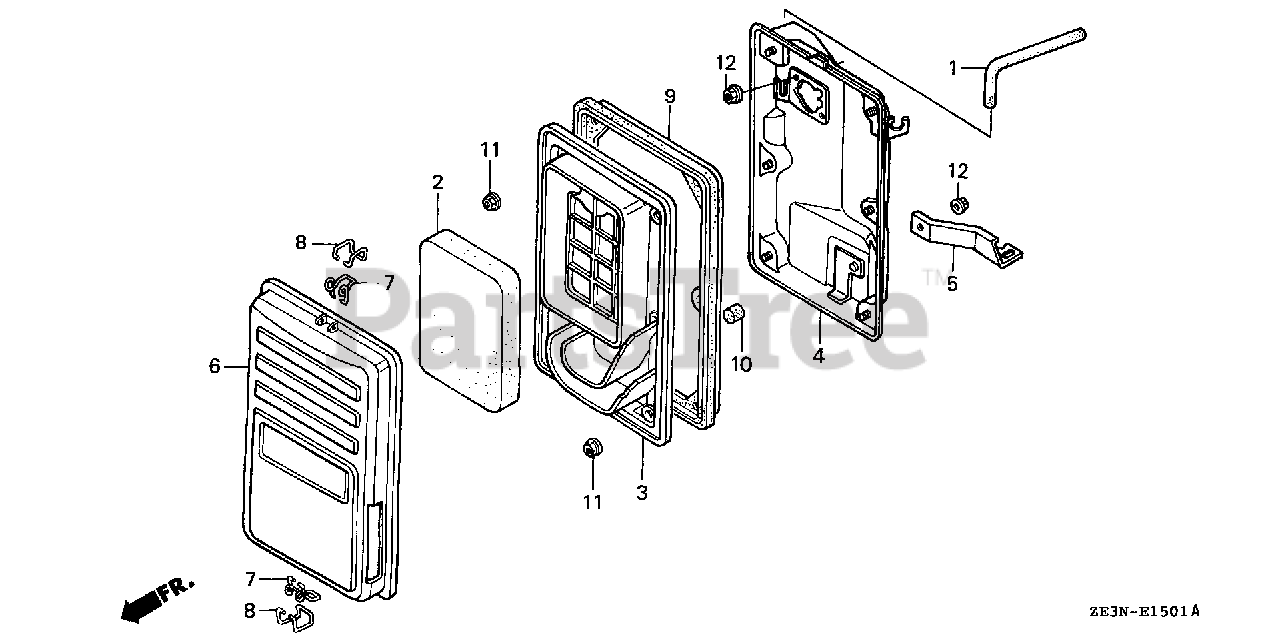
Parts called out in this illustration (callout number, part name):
1	TUBE, BREATHER
2	ELEMENT, AIR CLEANER
3	SEPARATOR, AIR CLEANER
4	HOUSING, AIR CLEANER
5	STAY, AIR CLEANER
6	COVER, AIR CLEANER
7	CLIP A, AIR CLEANER WIRE
8	CLIP B, AIR CLEANER WIRE
9	SEAL, AIR CLEANER
10	FILTER, DRAIN TUBE
11	NUT, FLANGE (5MM)
12	NUT, FLANGE (6MM)
